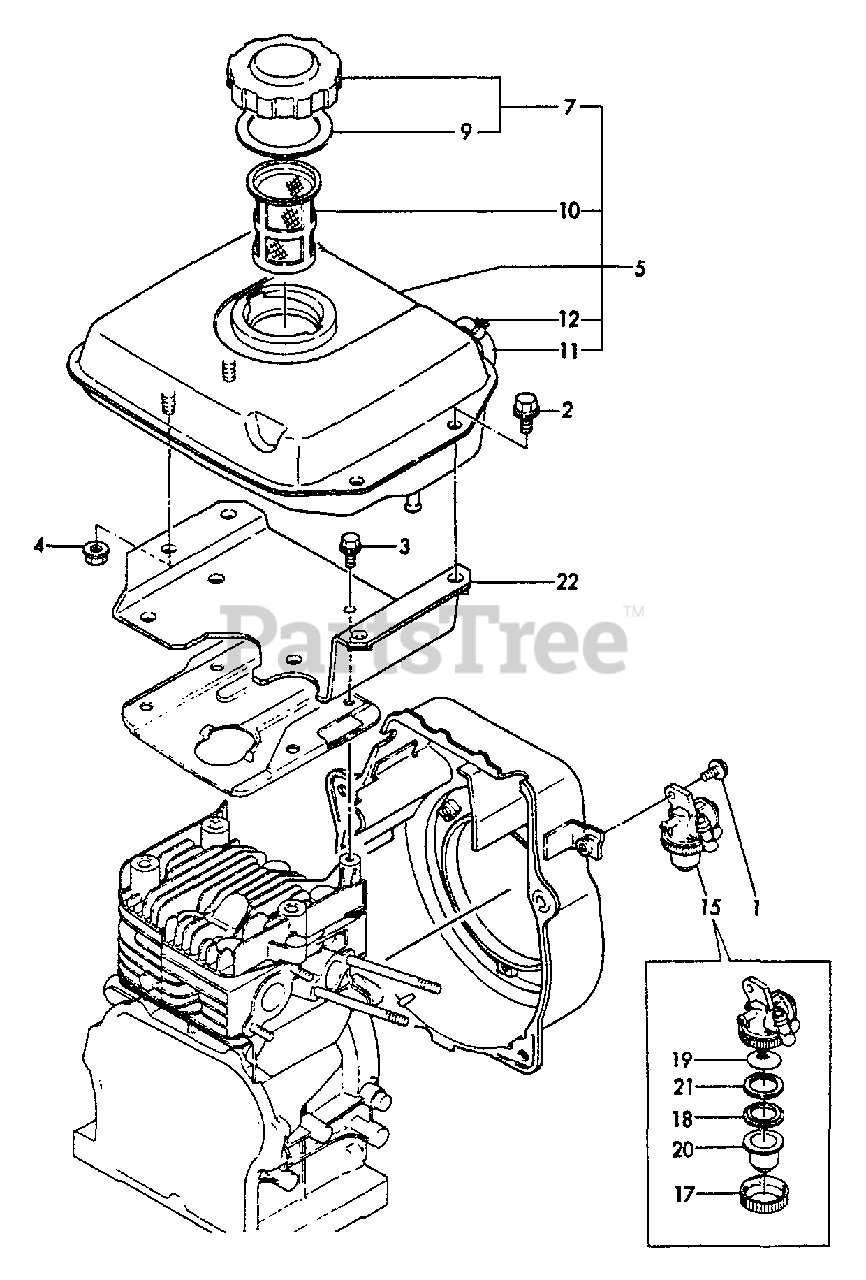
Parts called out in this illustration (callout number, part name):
1	BOLT - 6X12 -- PLATED
2	BOLT - 8X14 -- PLATED
3	BOLT - 6X8 -- PLATED
4	NUT - 8
5	FUEL TANK ASSY
7	CAP ASSY
9	GASKET
10	STRAINER, FUEL
11	GAUGE, LEVEL
12	CLAMP, HOSE - 9
15	FUEL COCK ASSY
17	RETAINER
18	GASKET
19	FILTER, FUEL
20	BOWL, STRAINER
21	PLATE
22	BRACKET, FUEL TANK
